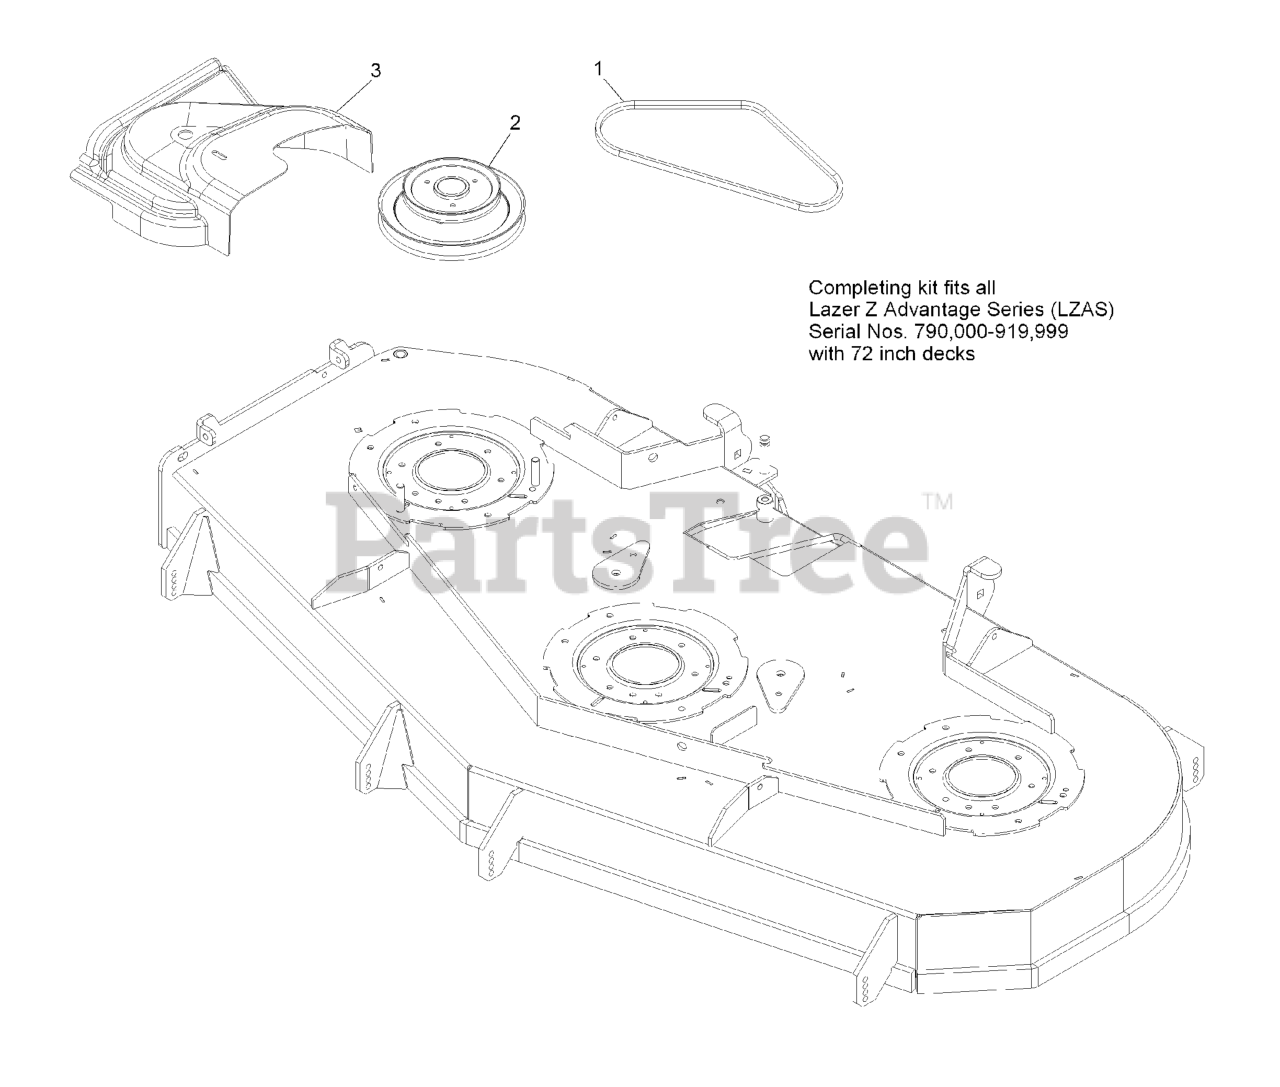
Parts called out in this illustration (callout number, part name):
1	BELT, BLOWER DRIVE 72
2	JACKSHAFT,UV DRIVE 724
3	COVER,BELT UV 72
